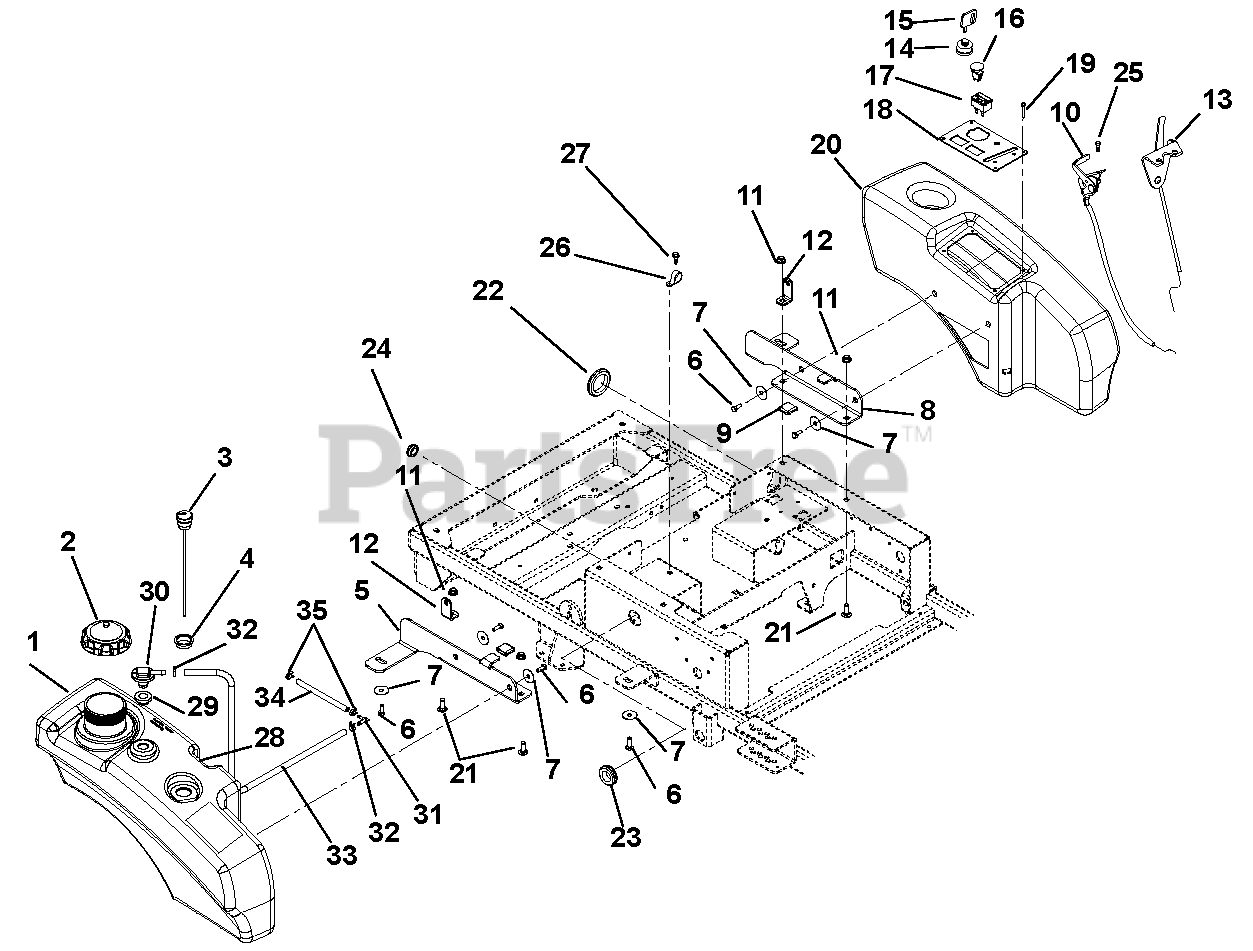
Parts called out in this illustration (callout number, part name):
1	Tank, XL Non-Permeable Fuel
2	Cap, 3.50" Vent-in Ratchet
3	Gauge, Remote Fuel 10.0"
4	Grommet, Fuel Gauge
5	Bracket, Right Hand Rear Tank Mount
6	Bolt, Serrated Hex Flange Washer Head .312-18 x .50
7	Washer, Flat Steel .347 x 1.254 x .048
8	Bracket, Left Hand Rear Tank Mount
9	Grip, Rubber
10	Cable, Throttle
11	Nut, .38-16 Nyloc Flange
12	Bracket, Hood Pivot
13	Cable, Choke
14	Key Switch
15	Key, w/Cap
16	Switch, Clutch
17	Hour Meter, Digital
18	Panel, Control
19	Screw, Hex .25 x 14-.75
20	Fender, XL
21	Bolt, Round Head Square Neck .38-16 x 1.00 Grade 5
22	Grommet, 2.00"
23	Grommet .125 x 1.000 ID
24	Grommet, Rubber 5/8 ID/1.13 OD
25	Screw, Tapping 10-24 x .50 Hex Washer Head Thread
26	Clamp, Cushioned Steel
27	Screw, Tap Hex Washer Head .38-16 x .5
28	Tube, Fuel Pick-up (XL)
29	Grommet, Remote Vent, Nitrile
30	Vent, Roll-over (.25" ID hose)
31	Fitting, 3/16 x 1/4 90 Degree VAC
32	Clamp, Fuel Line
33	Hose, .25 Low-Perm Bulk Gas
34	Hose, .188 Low-Perm Bulk Gas
35	Clamp, Hose, Spring .188
